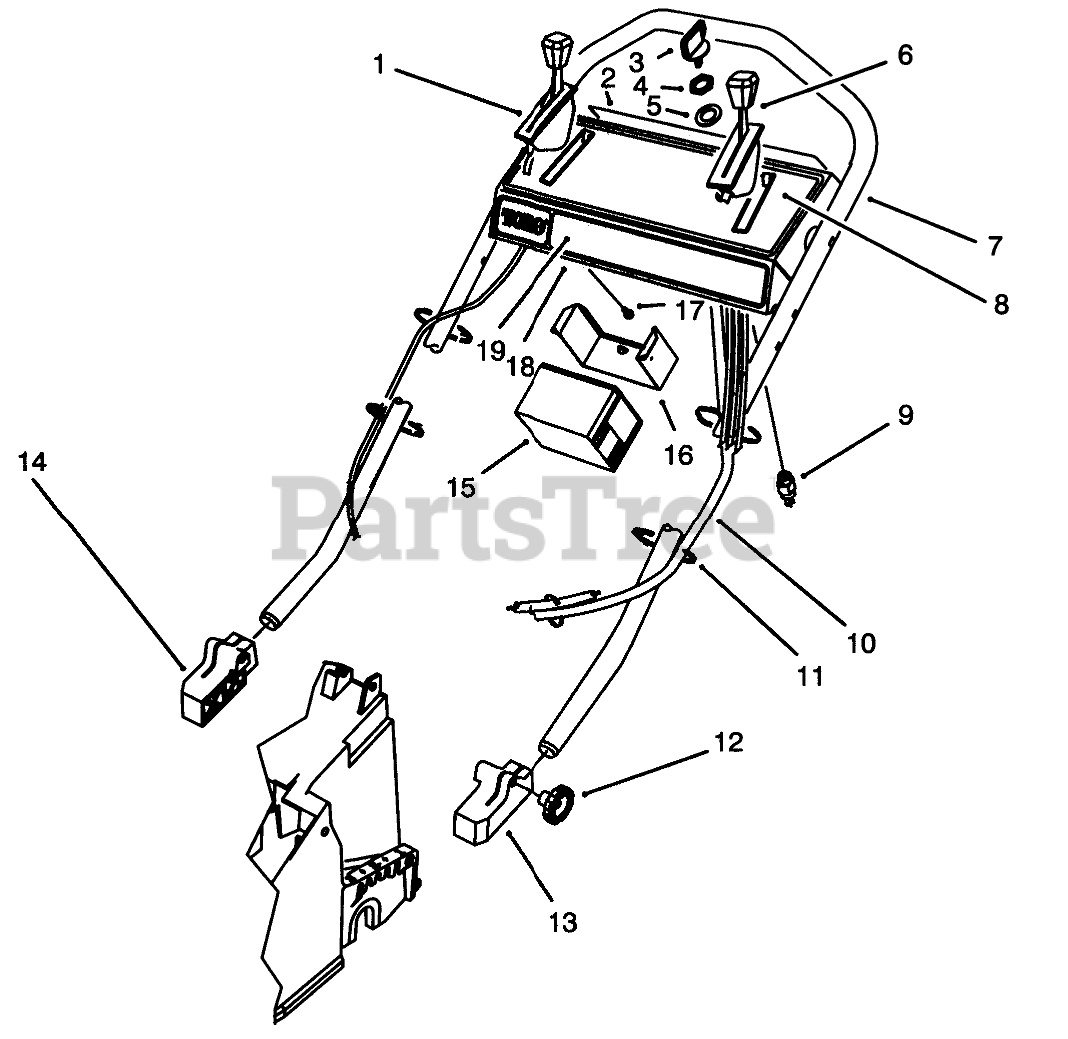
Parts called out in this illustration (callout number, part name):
1	GROUND SPEED CONTROL
2	DECAL - PANEL, REAR
3	KEY-IGNITION
4	NUT-HH
5	WASHER-TOOTH, INTERNAL
6	THROTTLE CONTROL
7	HANDLE PVC DIP
8	DECAL-INSTRUCTION KEY
9	Switch-Starter (Incl. Ref. #4 & 5)
10	Harness-Wire
11	TIE-CABLE
13	MOUNT-HANDLE, LH
14	MOUNT-HANDLE, RH
15	Battery
16	BATTERY RETAINER
17	SCREW-HWHTF
18	Panel-Control (Incl. Ref. #2, 8 & 19)
19	DECAL - PANEL KEY
